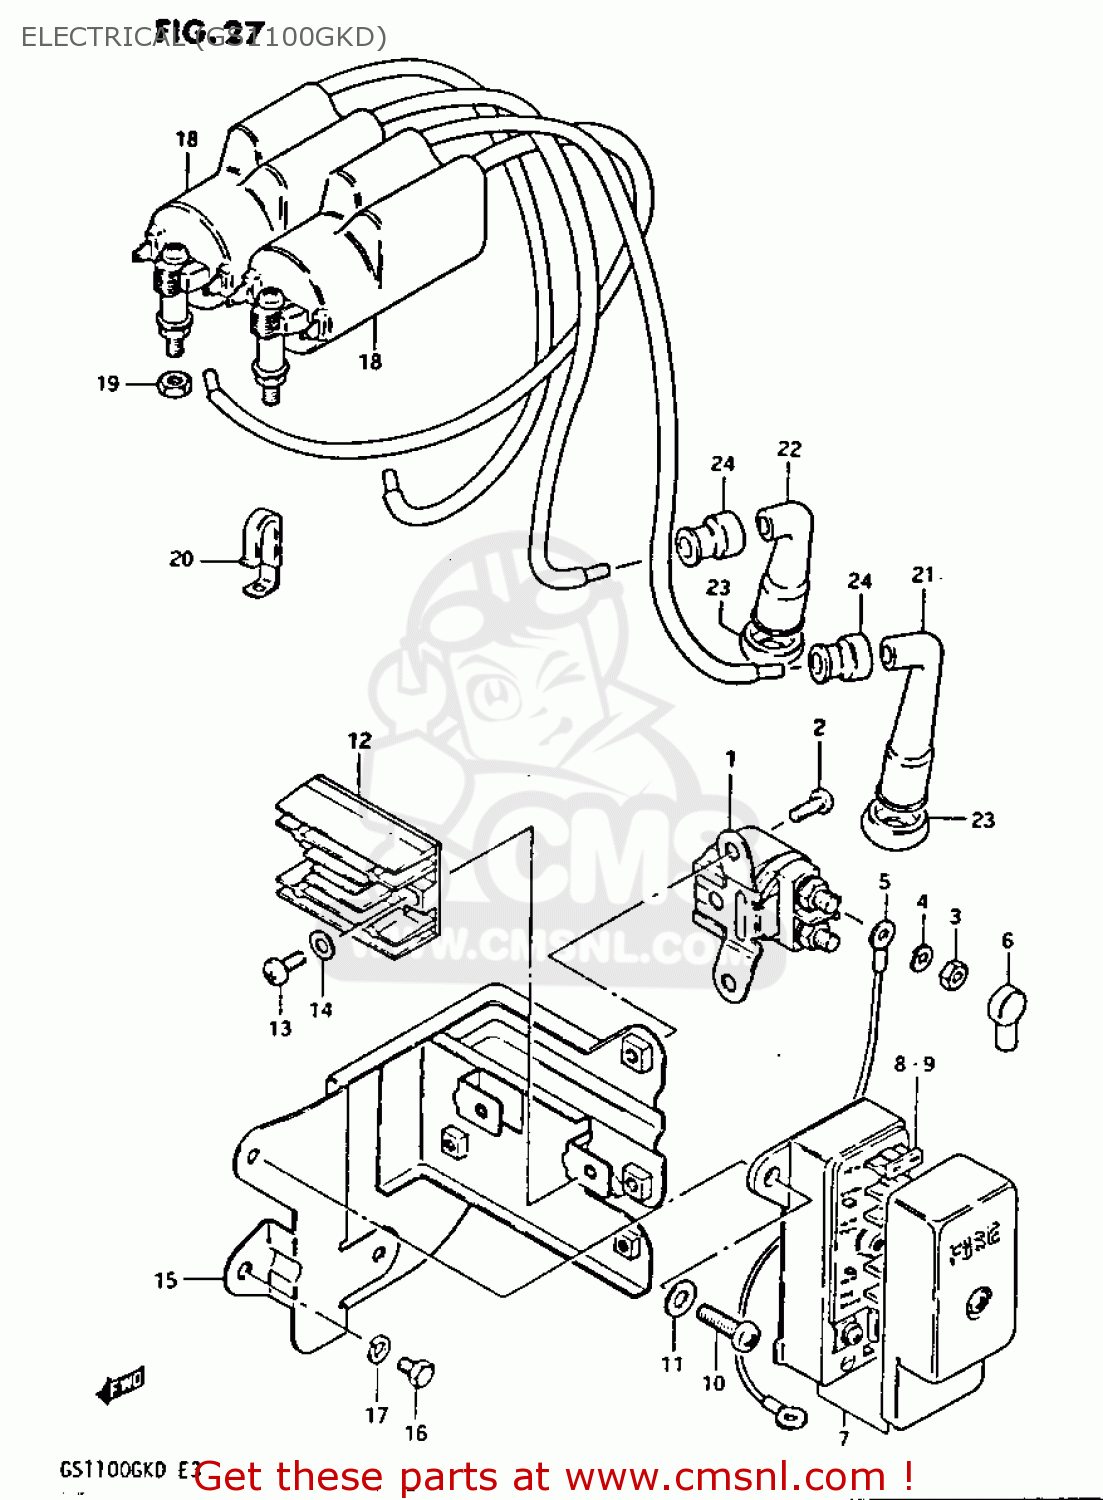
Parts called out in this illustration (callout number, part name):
1	RELAY ASSY,STARTING MOTOR
2	SCREW
3	NUT 6MM
4	WASHER,LOCK
5	CABLE,STARTING MOTOR
6	CAP,TERMINAL
7	BOX ASSEMBLY,FUSE
8	FUSE(10A)
9	FUSE(15A)
10	SCREW 6X12
11	WASHER
12	RECTIFIER ASSEMBLY
13	SCREW
14	WASHER
15	HOLDER COMP,ELECTRONIC PARTS
16	BOLT
17	WASHER,LOCK
18	COIL ASSEMBLY,IGNITION
19	NUT
20	CLAMP
21	CAP ASSY,SPARK PLUG
22	CAP,SPARK PLUG
23	SEAL,SPARK PLUG
24	SEAL,SPARK PLU
